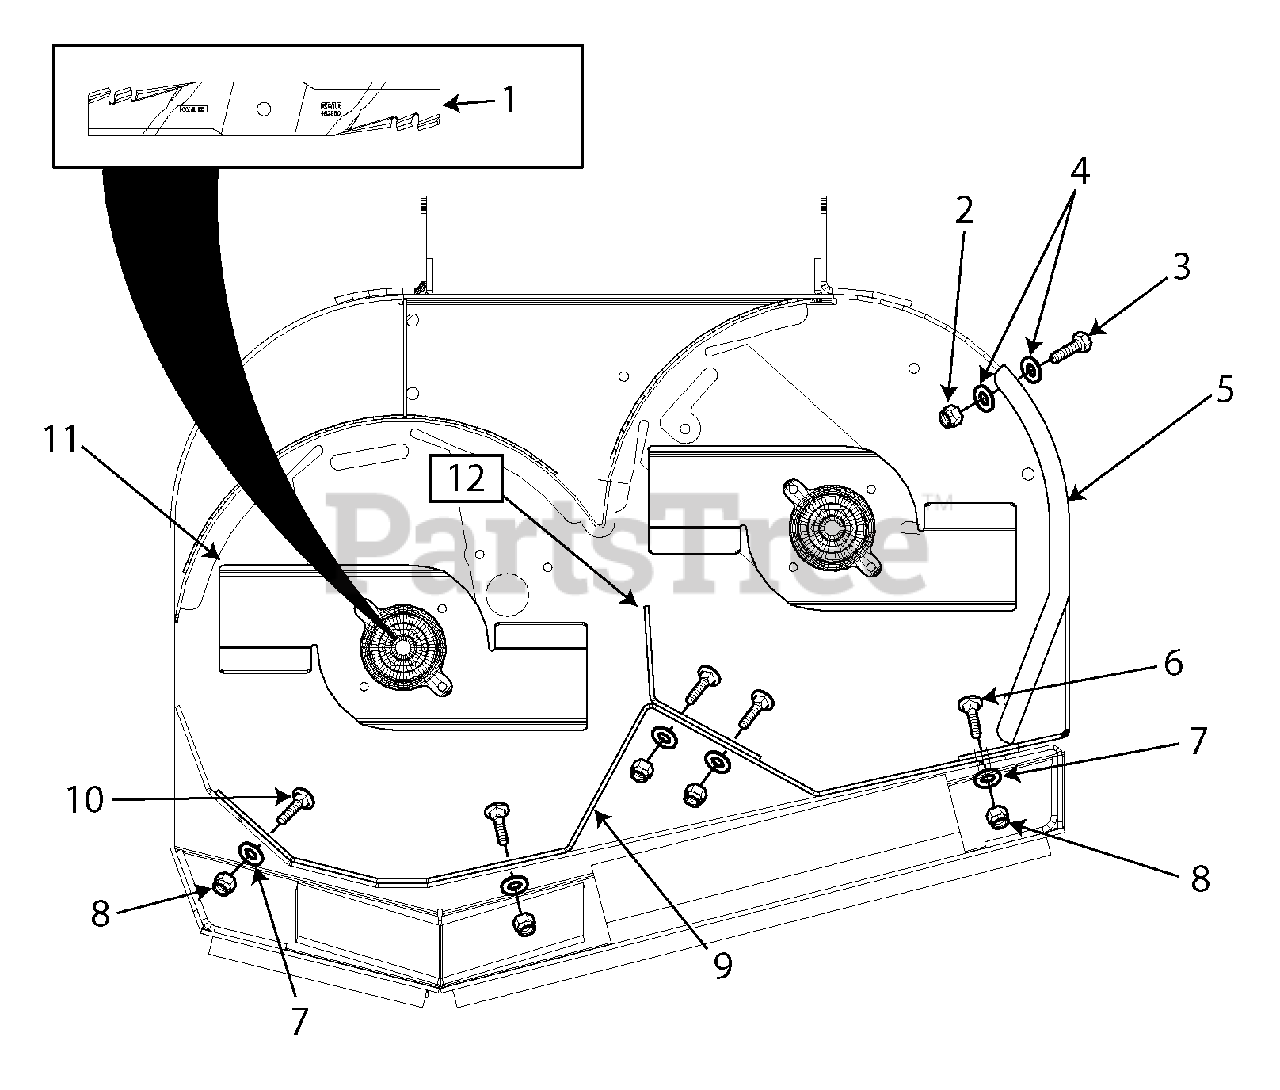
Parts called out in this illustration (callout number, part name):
1	Eliminator Mulch Blades
2	Elastic Stop Nut 5/16-18
3	H.H. Bolt 5/16-1"
4	Flatwasher 5/16"
5	Mulch Plate
6	Carriage Bolt 3/8-16 x 1-1/4"
7	Flatwasher 3/8"
8	Elastic Stop Nut 3/8-16
9	Mulch Baffle
10	Carriage Bolt 3/8-16 x 1"
11	Hurricane Plate
12	Divider Plate
